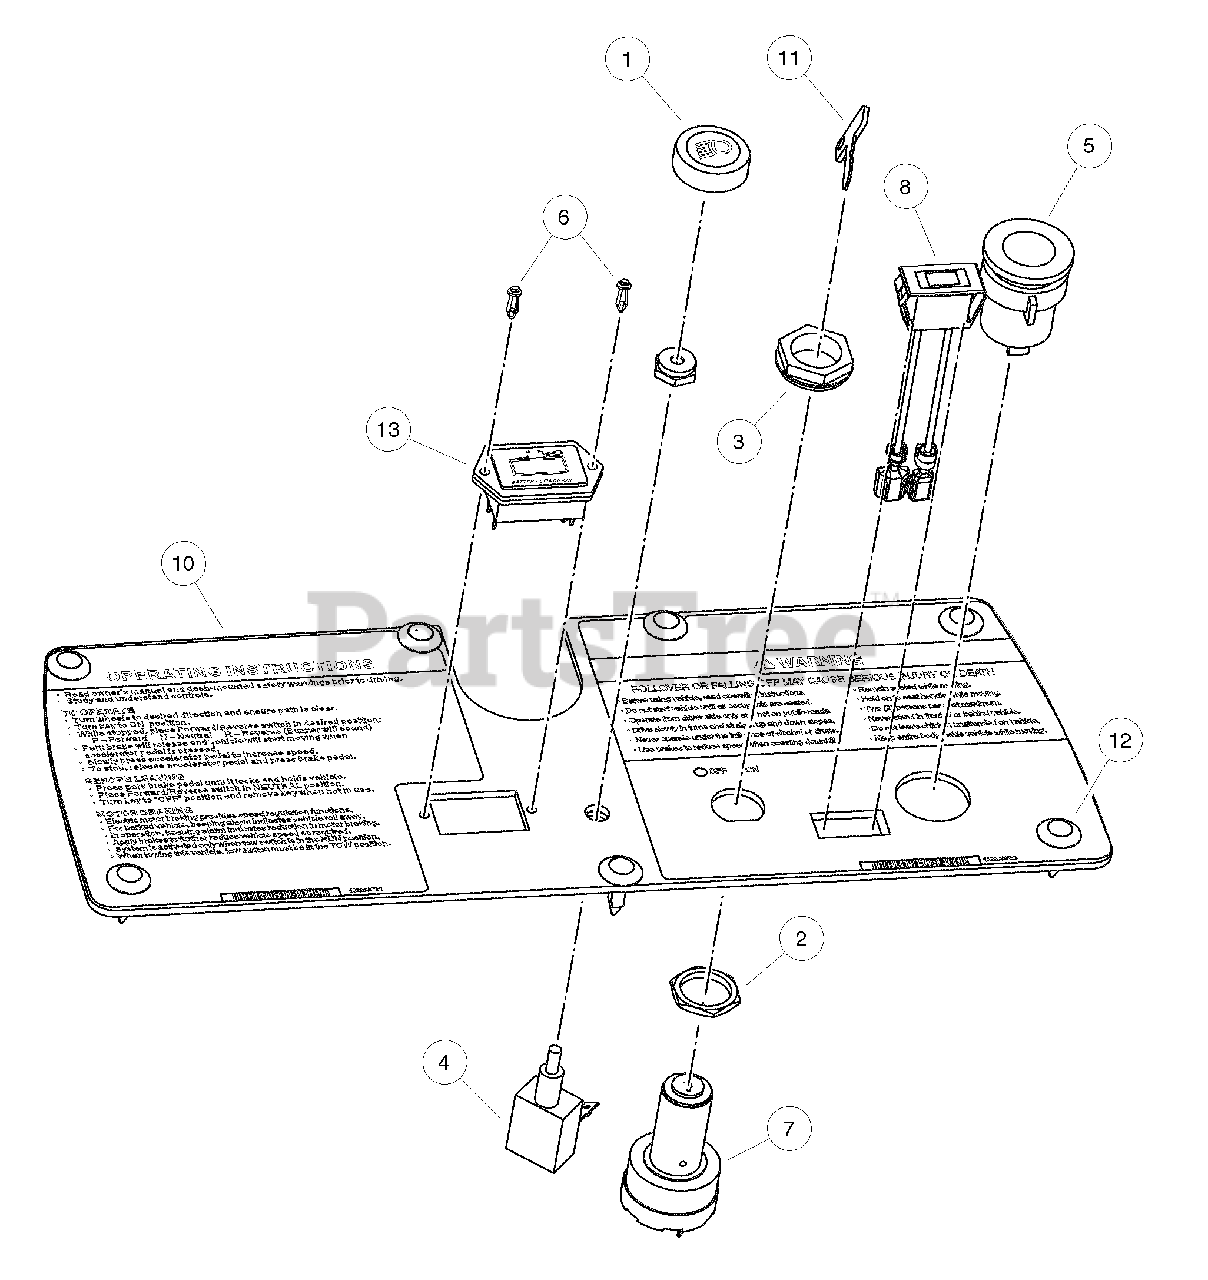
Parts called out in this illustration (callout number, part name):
1	Knob, Light Switch
2	Nut, Key Switch
3	Nut, Key Switch
4	Switch, Light
5	Receptacle, Accessory
6	Rivet, Micro Tuflok
7	Key Switch, Electric
8	Light, Battery
9	Panel, Instrument
10	Panel, Instrument
12	Rivet, Removable, Tuflok 1/4"
13	Indicator, Batt Chrg, 48v
